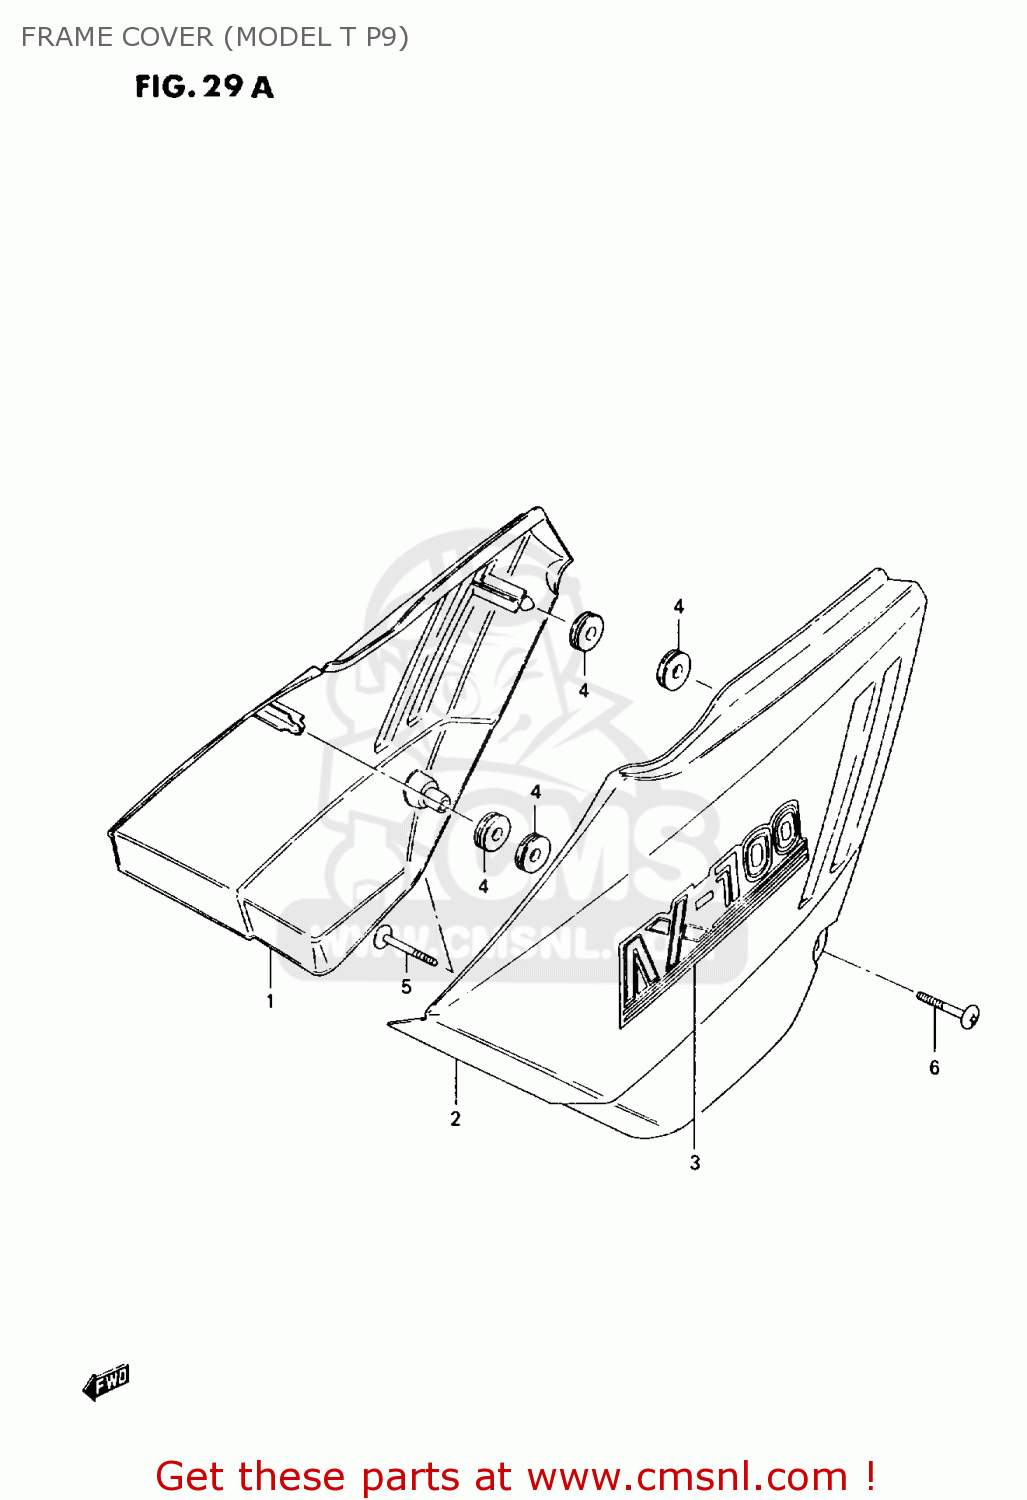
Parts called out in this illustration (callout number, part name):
1	COVER,FRAME,R
2	COVER,FRAME,L
3	EMBLEM
4	CUSHION
5	SCREW
6	SCREW(6X45)
